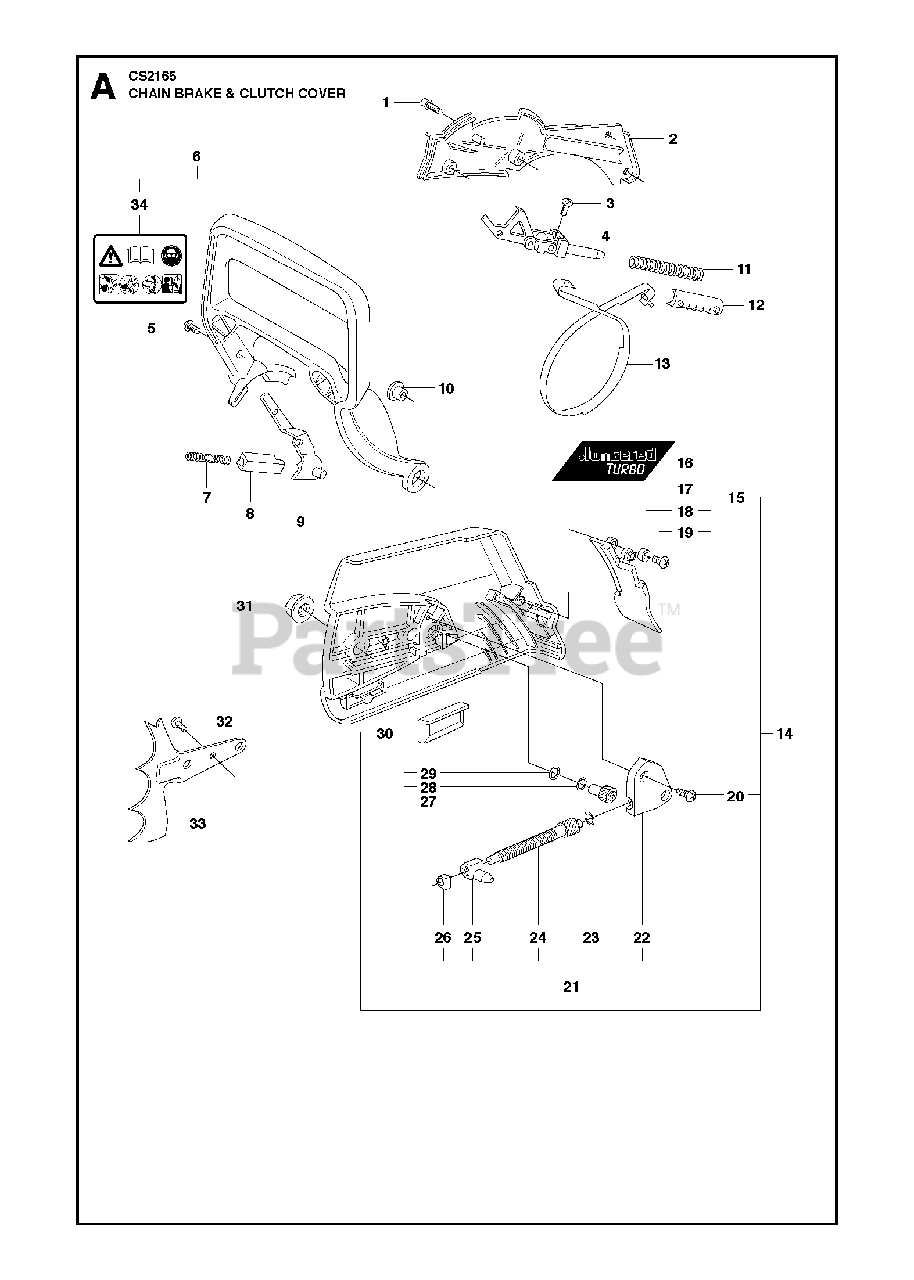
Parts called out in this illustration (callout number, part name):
1	SCREW
4	KNEE LINK
6	HAND GUARD
7	LOCK SPRING
9	BRAKE LEVER
11	BRAKE SPRING
13	BRAKE BAND
14	CLUTCH COVER
15	CLUTCH COVER
16	DECAL
17	PROTECTOR
18	WASHER
19	SCREW
20	SCREW
21	KIT-CHAIN TENSIONER
22	COVER
23	WASHER
24	WORM SCREW / ADJUSTER
25	COUPLING
26	SLEEVE
27	SCREW
28	WASHER
29	O-RING
30	CHAIN GUIDE
31	NUT M8 FLANGE
33	FELLING DOG
